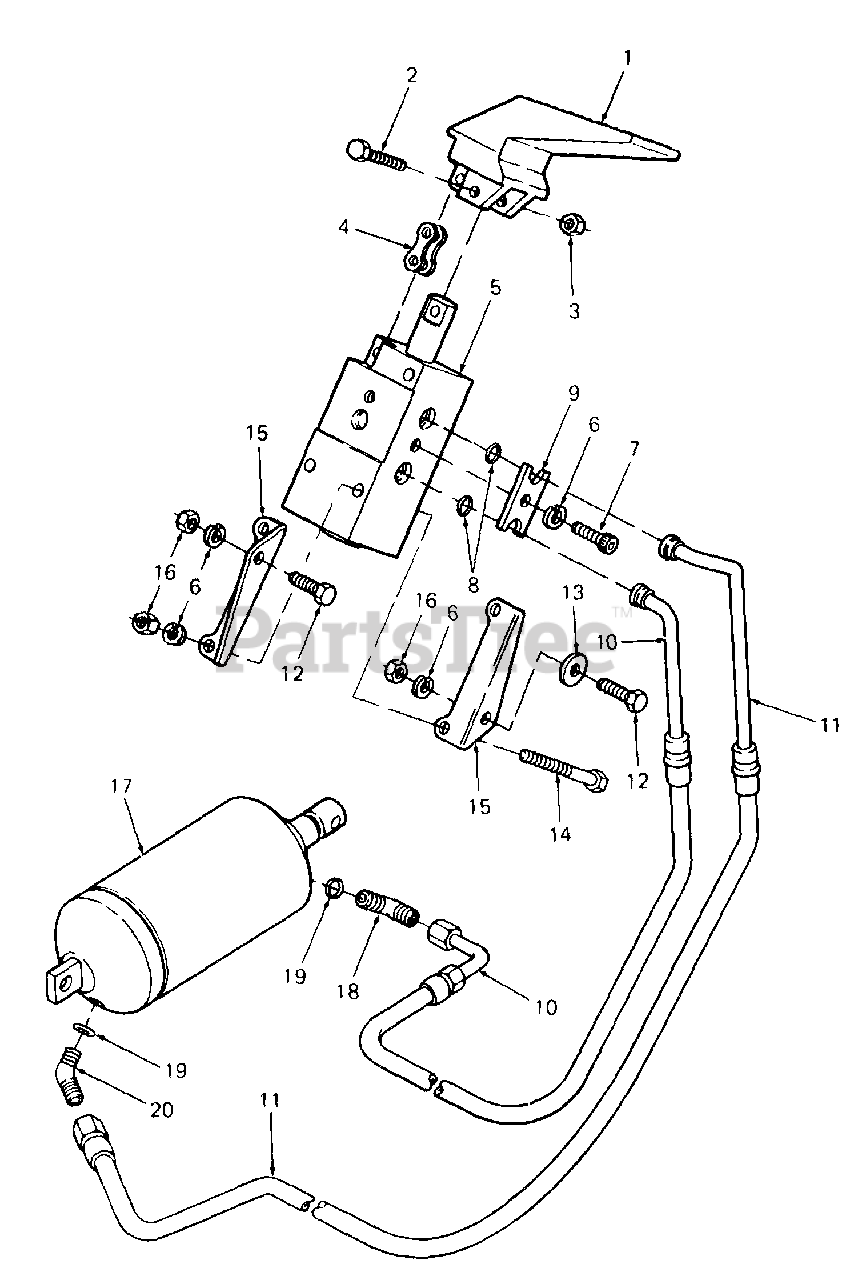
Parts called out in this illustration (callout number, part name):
1	Handle, Valve
2	Screw, Hex Cap, #10-24 x 1.0 Lg
3	Nut, Hex Center Lock, #10-24
4	Link, Chain
5	Valve, Lift
6	Washer, Lock, 1/4
7	Screw, Socket Hd Cap, 1/4-20 x .62 Lg GR8
8	O-Ring, .301 x .070 Dia
9	Clamp, Double
10	Hose, Cylinder-Contracting
11	Hose, Cylinder-Extending
12	Screw, Hex Cap, 1/4-20 x .62 Lg GR5
13	Washer, Bell, .265 x .75 x .062 Thk
14	Screw, Hex Cap, 1/4-20 x 2.25 Lg
15	Bracket, Valve Mtg
16	Nut, Hex, 1/4-20 GR5
17	Cylinder, Hydraulic
18	Elbow, 90 Deg w/O-Ring
19	O-Ring, 1/4 OD Tube
20	Elbow, 45 Deg w/O-Ring
